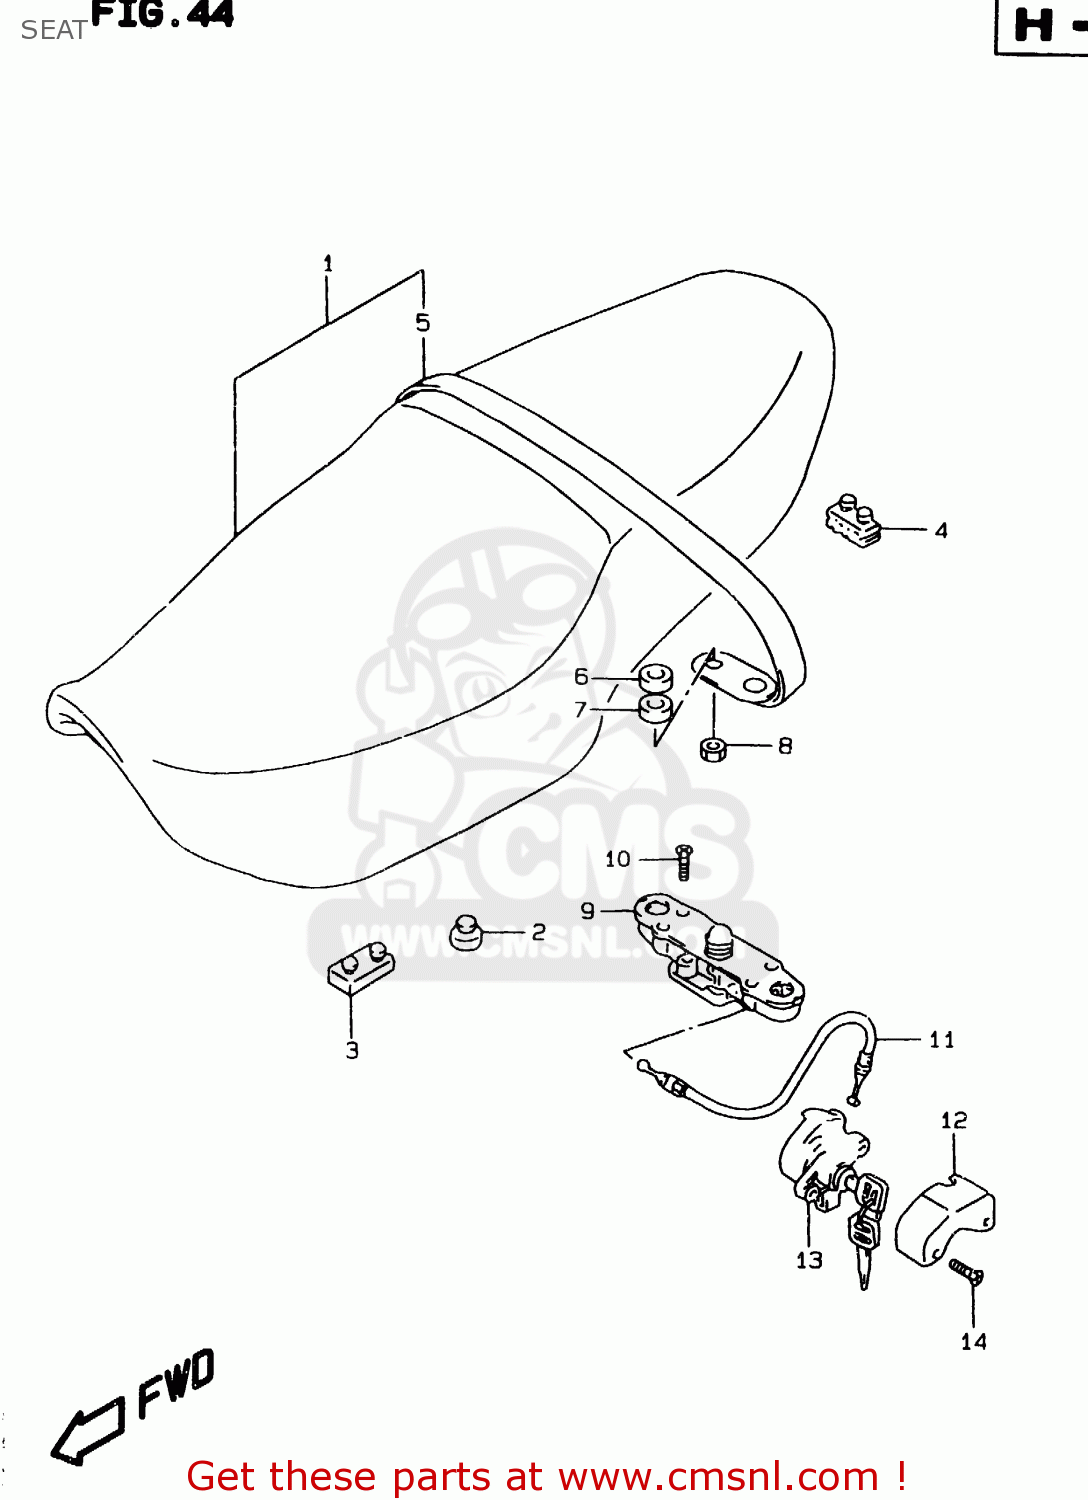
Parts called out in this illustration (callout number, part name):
1	SEAT ASSY
2	CUSHION
3	CUSHION
4	CUSHION,SEAT(40X20X15)
5	BAND ASSY,SEAT(BLACK)
6	CUSHION
7	CUSHION
8	NUT
9	LOCK ASSY,SEAT STRIKER
10	SCREW 6X30
11	CABLE,SEAT LOCK
12	GUARD,SEAT LOCK
13	LOCK SET,SEAT & HELMET
14	SCREW(6X14)
